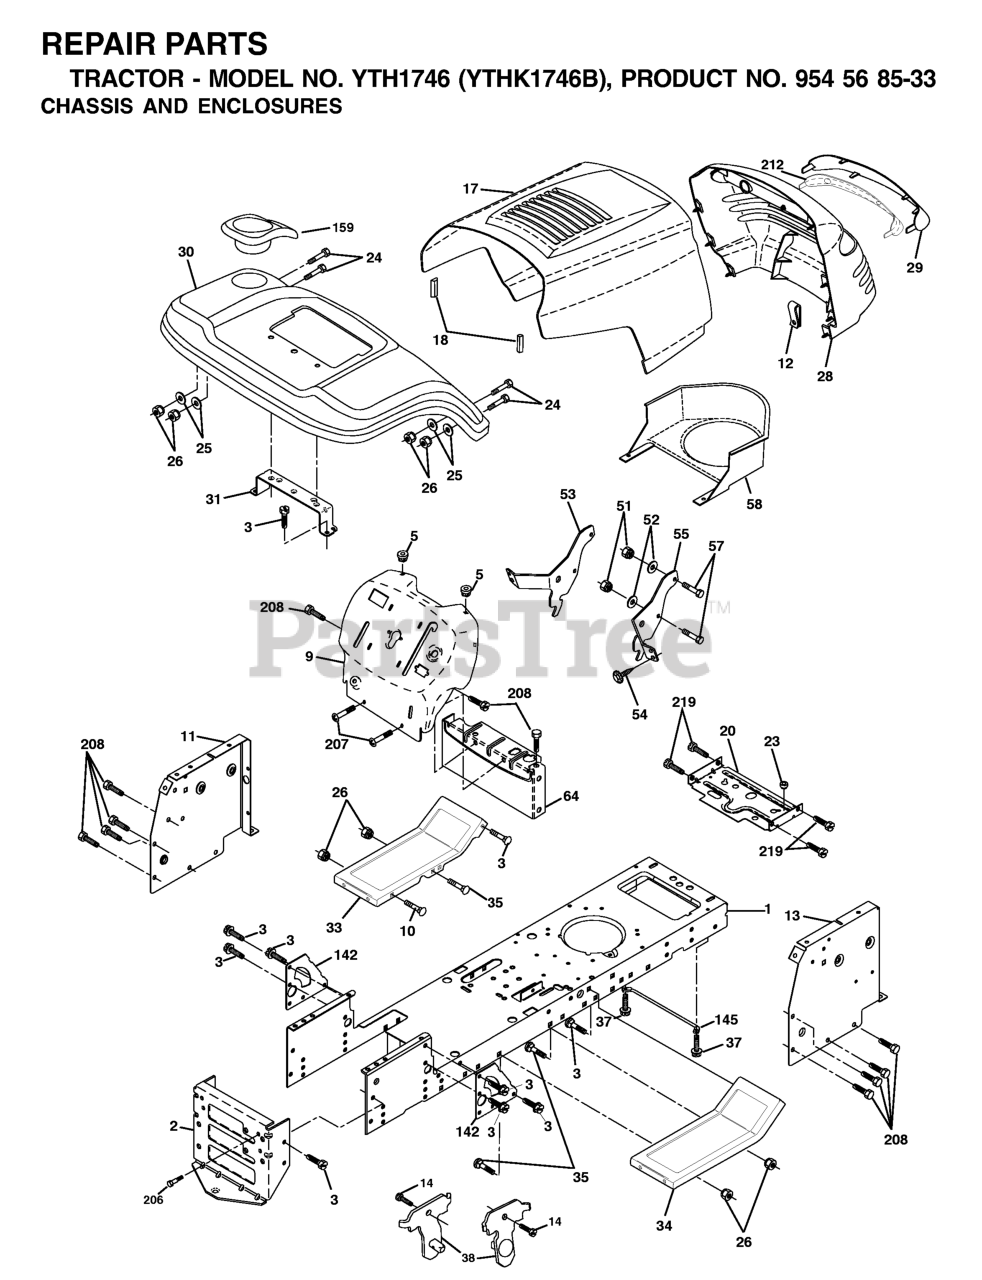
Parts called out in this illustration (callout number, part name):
2	SHAFT.ASM.LIFT.CROSS.H
3	LEVER.LIFT.HANDLE.GT
7	GRIP.LEVER.5625.ID
10	SPRING.TORSION.LIFT.HANDLE
87	PIN.COTTER.7/16.BOW TI.
88	SPRING.LIFT.ASSIST.GT2
89	WASHER.CLEAR.ZINC
90	PIN.COTTER.5/16.BOW TI
91	LINK.ASM.LIFT.REAR
97	SCREW 3/8-16X3/4
98	LINK.ASM.SUSP.FRONT.MW
